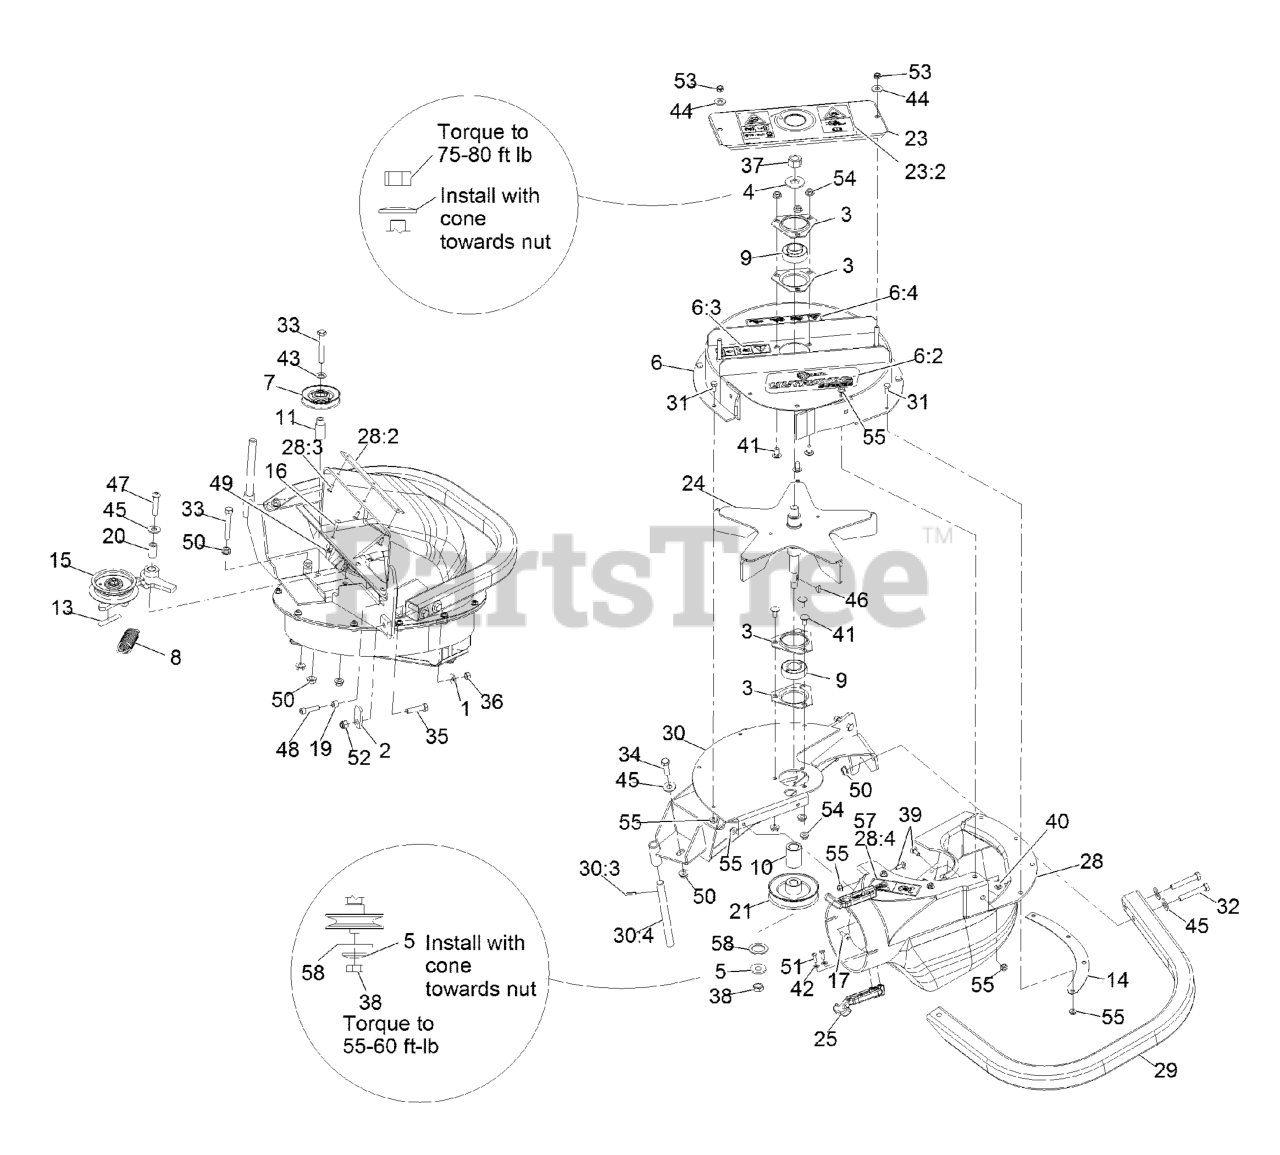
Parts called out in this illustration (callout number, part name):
1	WASHER-SPRING
2	LATCH-CATCHER, GRASS
3	HOUSING-FLANGE
4	WASHER-SPRING
5	WASHER-SPRING
6	ASM-UPPER HOUSING SMALL
6:2	DECAL-ULTRAVAC S-SERIES
6:3	DECAL-COVER, MISSING
6:4	DECAL-WARNING WEIGHT
7	IDLER-INSIDE
8	SPRING-IDLER
9	BEARING
13	DECAL-WARNING
14	PLATE-BACKING, BLOWER
15	ASM, Idler
16	SCREW-HEAD, TRUSS
19	BUSHING, LOCATOR
20	BUSHING-PIVOT, IDLER
21	SHEAVE-BLOWER
23	ASM, BEARING COVER
23:2	DECAL-WARNING BLOWER
24	IMPELLER
25	LATCH-RUBBER
28	ASM,BLOWER CHUTE LHP
28:2	PLATE-REINFORCEMENT
28:3	RIVET-BLIND
28:4	Decal-Blower-Impeller Hazard
30	WELD, FRAME SM BLOWER
30:3	PIN-ROLL
30:4	SHAFT-CATCHER, GRASS
31	SCREW-HH
32	SCREW-HH
33	SCREW-HH
34	SCREW-HH
35	SCREW-HH
36	NUT-HEX
37	NUT-HEX
38	NUT-JAM
39	BOLT-CARR
40	SCREW-CARR
41	SCREW-CARR
42	WASHER-FLAT
43	WASHER-FLAT
44	WASHER-FLAT
45	WASHER-FLAT
46	KEY-WOODRUFF
47	SCREW-HSBH
48	SCREW-HSH
50	NUT-HHF, WHIZ
51	SCREW-PPH
52	NUT-LOCK, NI
53	NUT-LOCK, NI
57	Decal-Blower-Impeller Hazard
58	WASHER-SPACER
